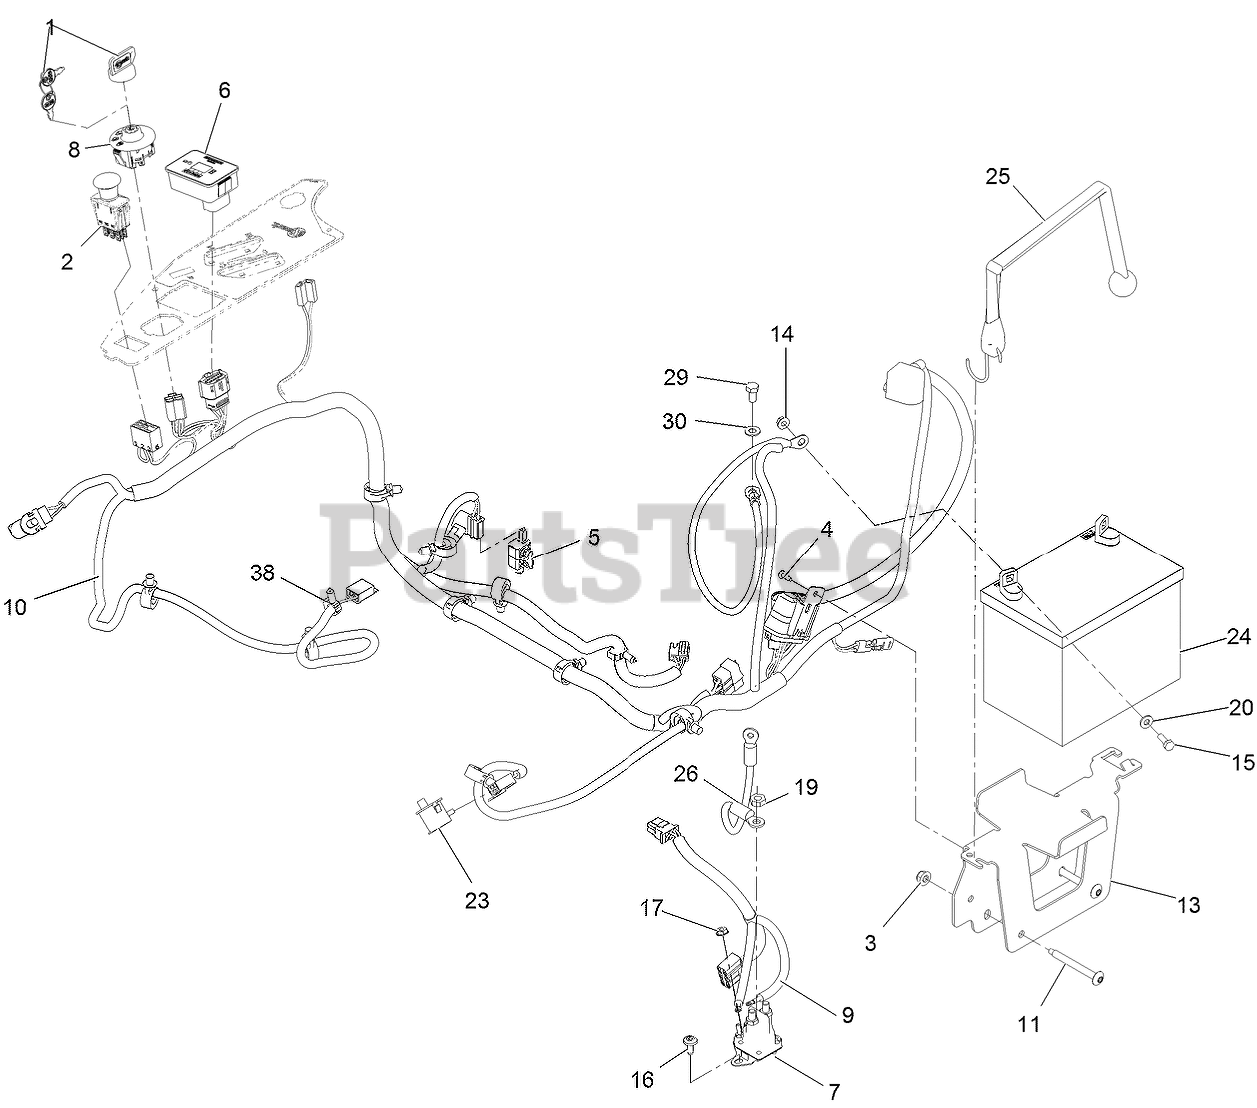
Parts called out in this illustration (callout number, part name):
1	KEYS-IGNITION (SPARE PAIR
1	KEY-IGNITION
2	SWITCH-PTO
3	NUT-HF, NI
4	SCREW-FORMING, THREAD
6	MODULE ASM
7	SOLENOID
8	SWITCH-IGNITION
9	ADAPTER-HARNESS, WIRE
10	HARNESS-WIRE
11	SCREW-TORX
13	TRAY-BATTERY
15	SCREW-HH
16	SCREW-TORX
17	NUT-KEPS
19	NUT-JAM
20	WASHER-FLAT
23	SWITCH-BAIL
24	Battery-195 CCA, Wet
25	STRAP-BUNGEE
26	CABLE-BATTERY, POSITIVE
29	SCREW-HH
30	WASHER-PLAIN
38	CLIP-HARNESS
